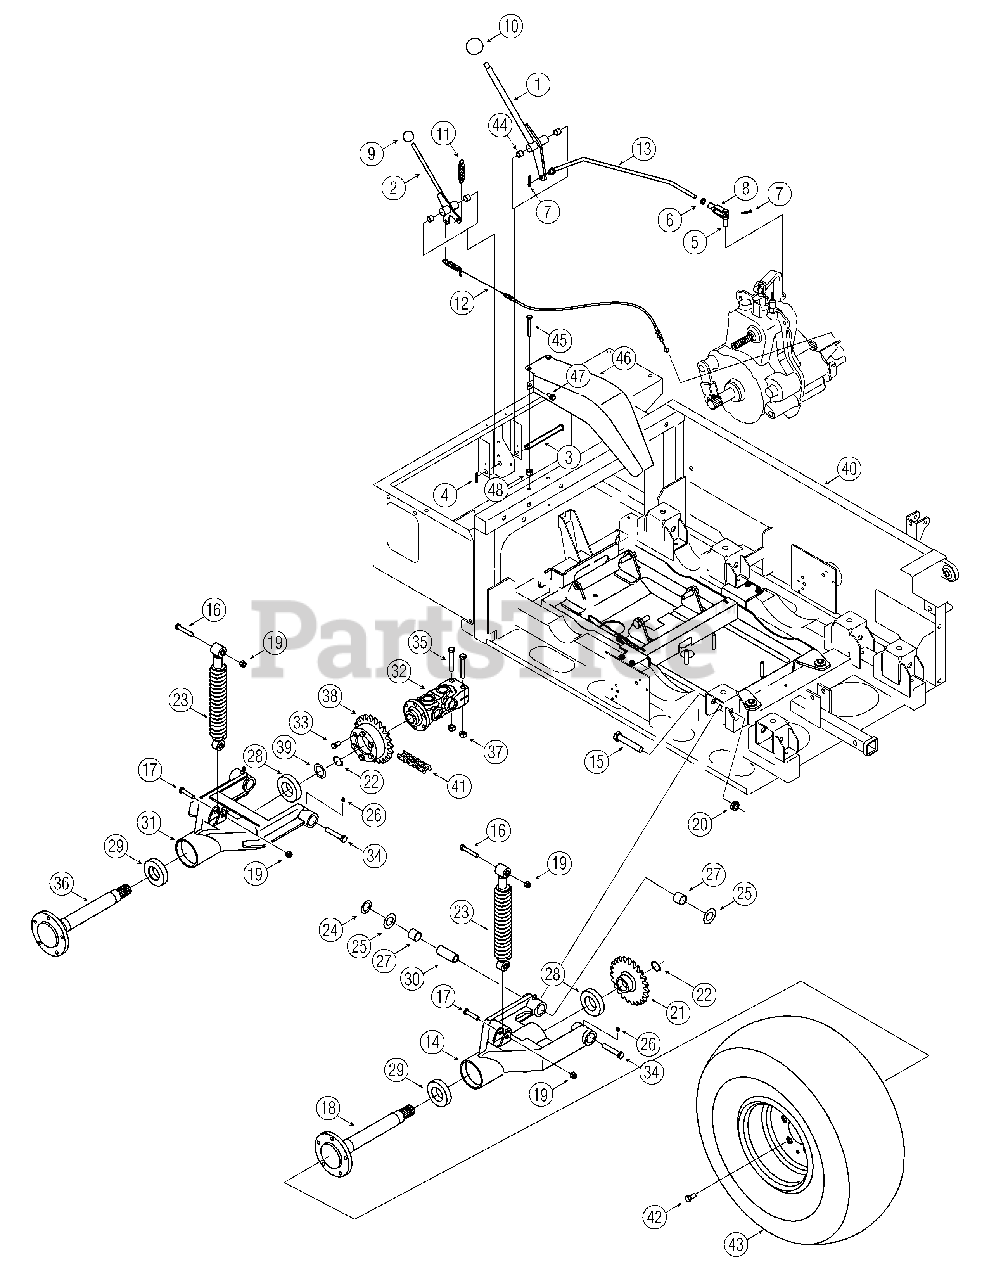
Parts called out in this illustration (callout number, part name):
1	Lever Assembly, Transmission
2	Shifter Assembly, Differential Lock
3	Pin, Clevis,.50 x 5.375
4	Pin, Cotter
5	Pin, Clevis, .375 x 2.0
6	Nut, Jam, 3/8-24
7	Pin, Cotter, .072 x 1.13
8	Clevis, Adjustment
9	Knob, Ball
10	Knob, Ball
11	Spring, Extension, .637 x 2.972
12	Control Cable, Differential Lock
13	Shifter Rod, Transmission
16	Screw, 3/8-16 x 2.25
17	Screw, 3/8-16 x 1.75
18	Axle Shaft, Rear Drive
19	Nut, Hex Lock, 3/8-16
20	Jam Nut, Lock, 5/8-18
22	Retaining Ring, External, 1.14
23	Shock Absorber, 2.9 Stroke
24	Washer, Flat, 1.06 x 1.56 x .020
25	Washer, Flat, 1.010 x 1.86 x .060
26	Lube Fitting, 3/16
27	Bearing Flange, 1.0 x 1.125 x 1.0
28	Ball Bearing, Internal Axle
29	Ball Bearing, External Axle
30	Spacer, .63 x 1.0 x 2.594
32	Weld Coupling Assembly
33	Screw, Hex, 3/8-16 x .75, Gr5
34	Screw, Hex, 5/8-18 x 3.5, Gr5
35	Screw, Hex, 7/16-14 x 2.75, Gr5
36	Axle Shaft, Drive Center
37	Nut, Hex Lock,7/16-14
38	Sprocket, Hub, 1.75 - 23T
39	Spacer, 1.78 x 1.88
40	Frame Assembly, Complete
41	Chain, 60-97 Pitch
42	Hex Screw, 7/16-20 x 1.5, Gr5
43	Wheel Ass’y, 25 x 11 x 10, RH, All Terr.
43	Wheel Ass’y, 25 x 11 x 10, LH, All Terr.
44	Bushing,.504 x.628 x.50
45	Hex Screw, 5/16-18 x 2.50
46	Belt Guard
47	Screw, 5/16-18 x.625
48	Hex Lock Nut, 5/16-18
